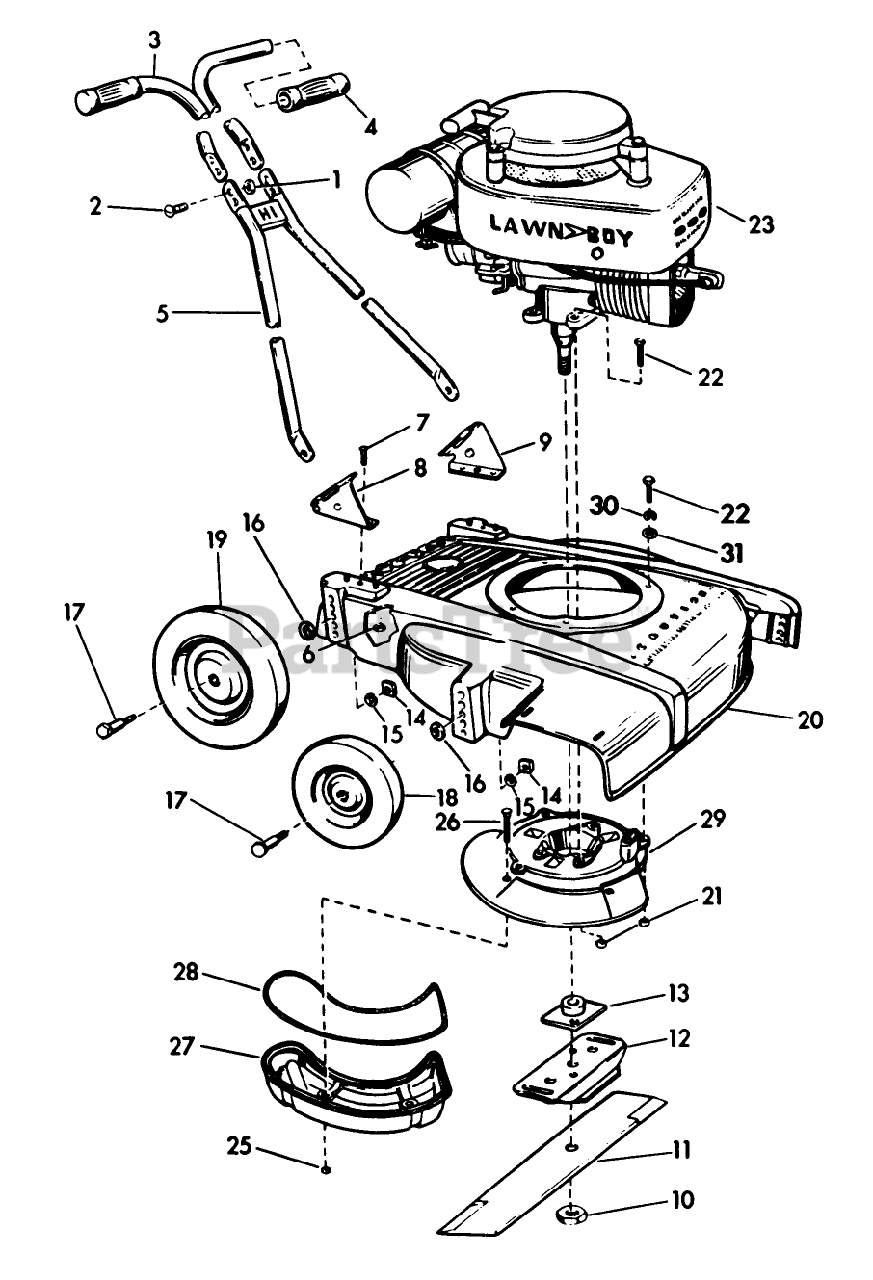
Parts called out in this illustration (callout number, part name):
1	STOP NUT
4	HANDLE GRIP
10	NUT-BLADE
13	PLATE AND COLLAR ASM
15	WASHER, LOCK
16	WASHER WROUGHT
20	Housing-18"
25	LOCKNUT E
